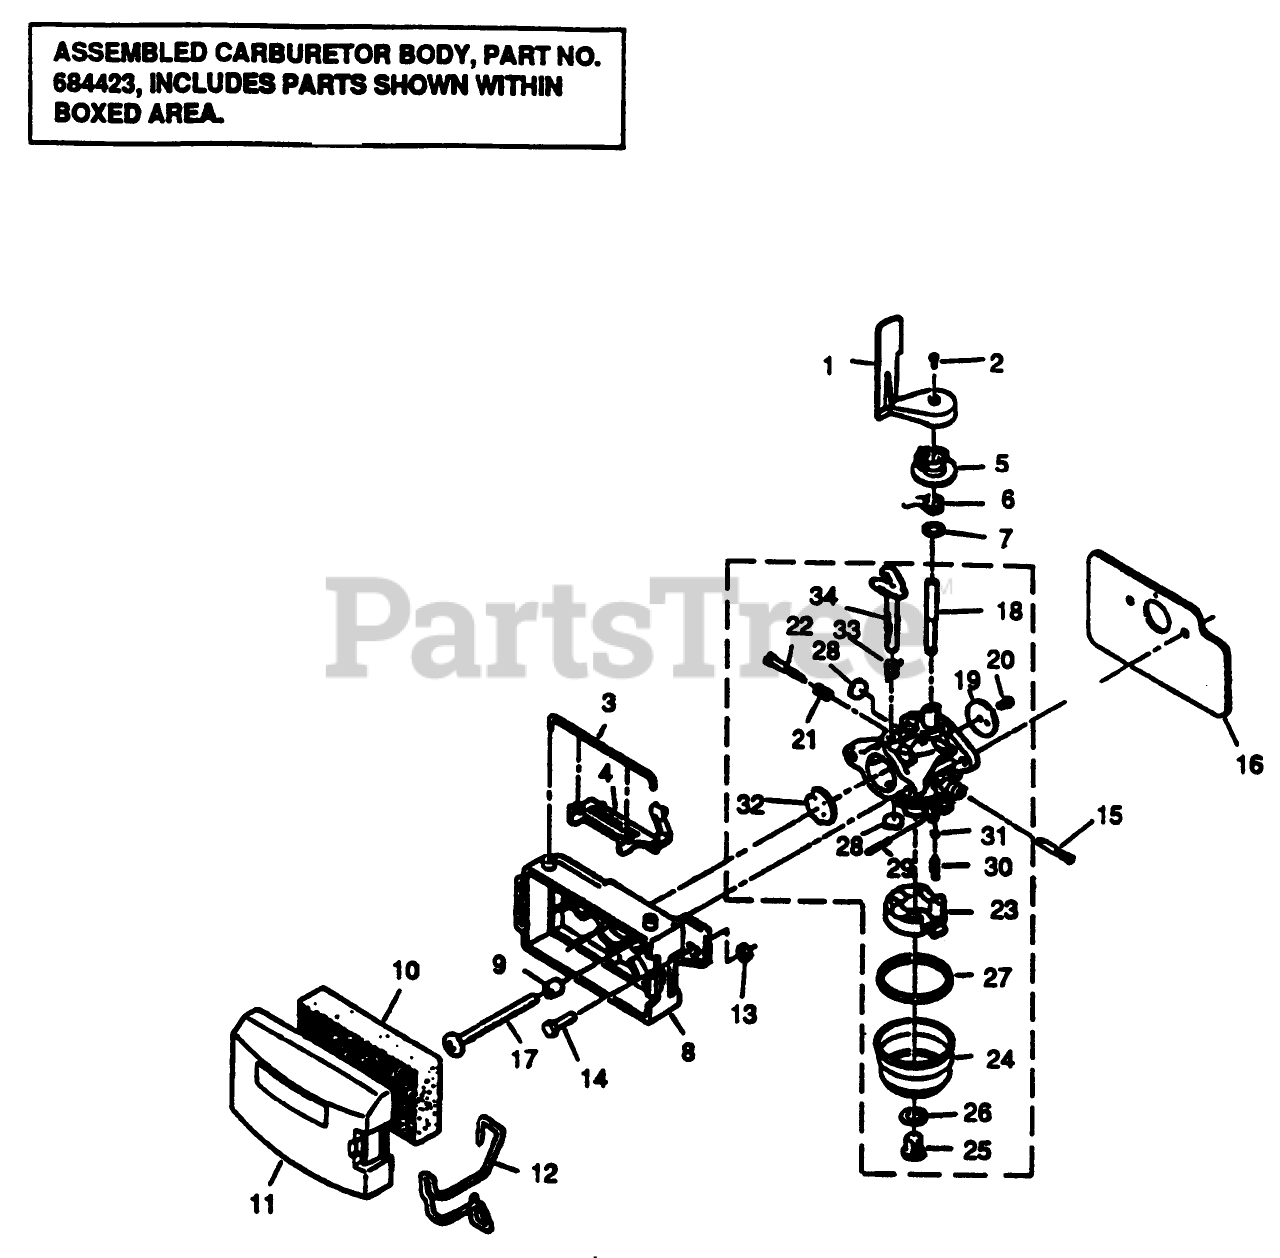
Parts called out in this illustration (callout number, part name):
1	AIR VANE F
2	SCREW F
3	RETAINER
5	COLLAR A/VAVE F
6	THROTTLE SPR E
7	WASHER VF
9	SPACER
12	RETAINER-COVER, FILTER
14	SCREW
15	SCREEN FUEL PITTS
16	Heat Shield
17	SCREW
18	Throttle Shaft
19	Throttle Valve
20	Screw-Throttle Valve
21	Spring Idle Needle
22	Idle Needle
24	Fuel Bowl
25	Screw-Bowl Retainer
26	Bowl Retainer Gasket
27	Fuel Bowl Gasket
28	Plug-Welch
29	Float Shaft
30	Inlet Needle Valve
31	Valve Seat
32	Choke Valve
33	Choke Return Spring
34	Choke Shaft
